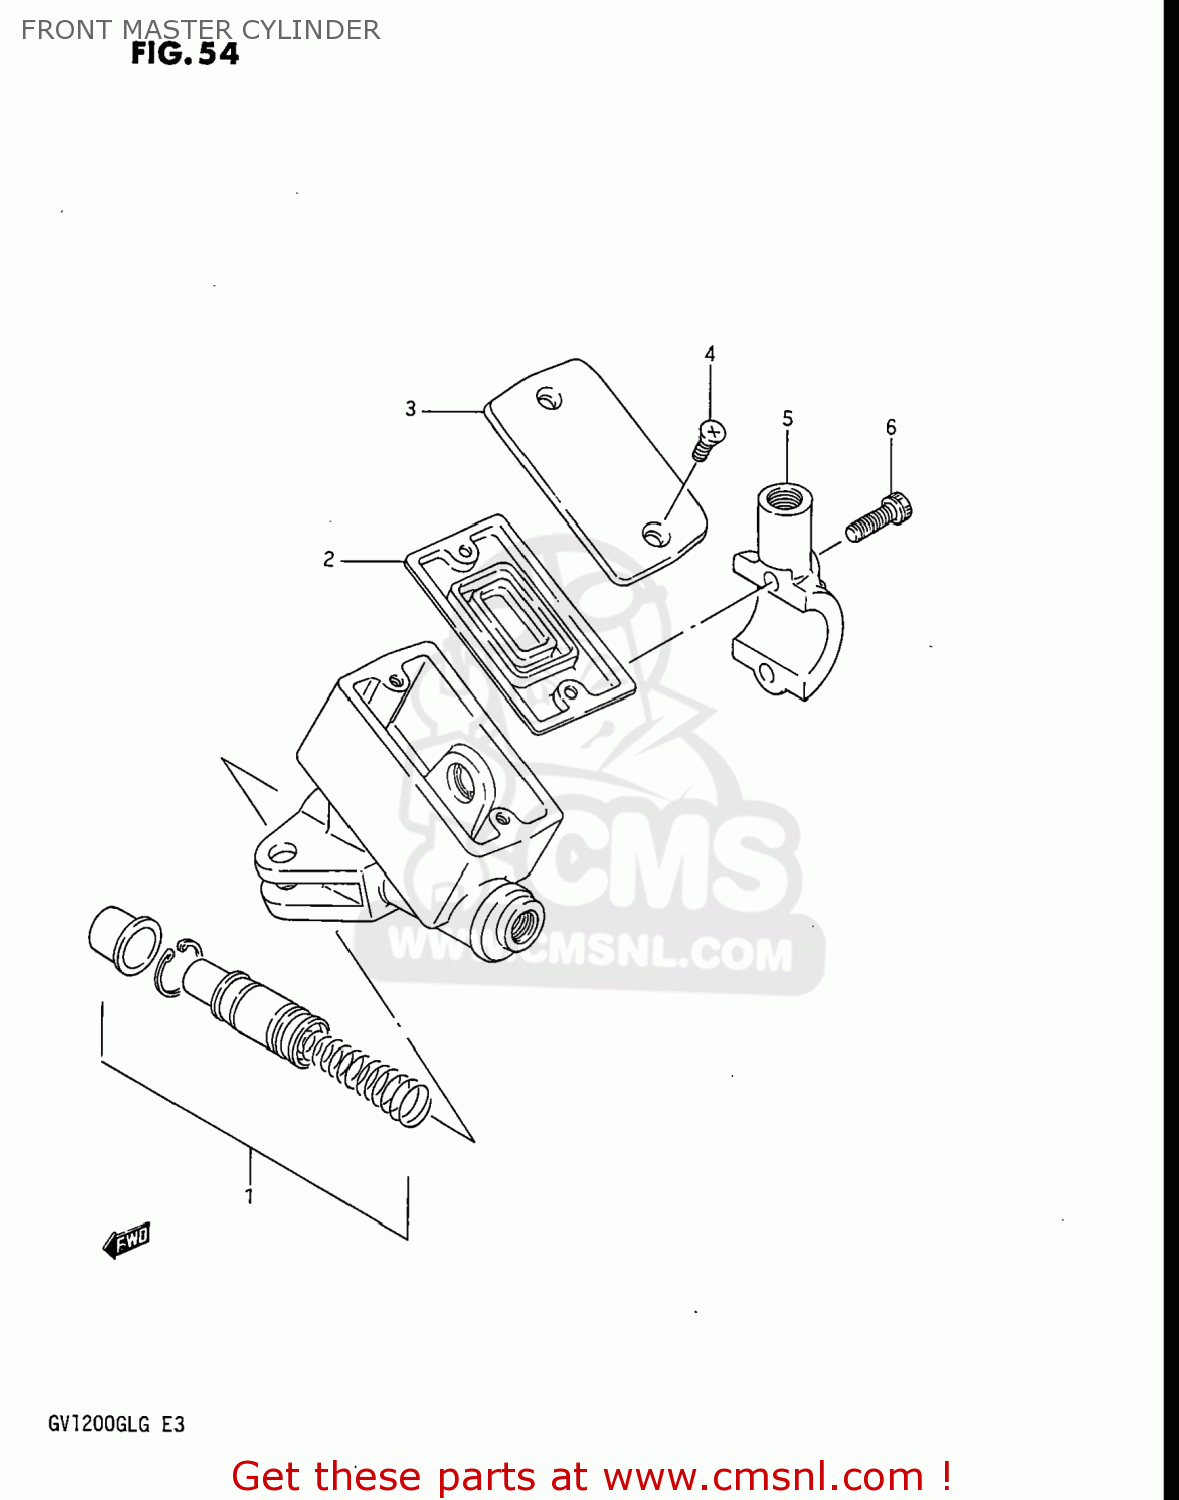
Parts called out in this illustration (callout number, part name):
1	PISTON & CUP SET
2	3
3	CAP
4	SCREW
5	HOLDER
6	BOLT
